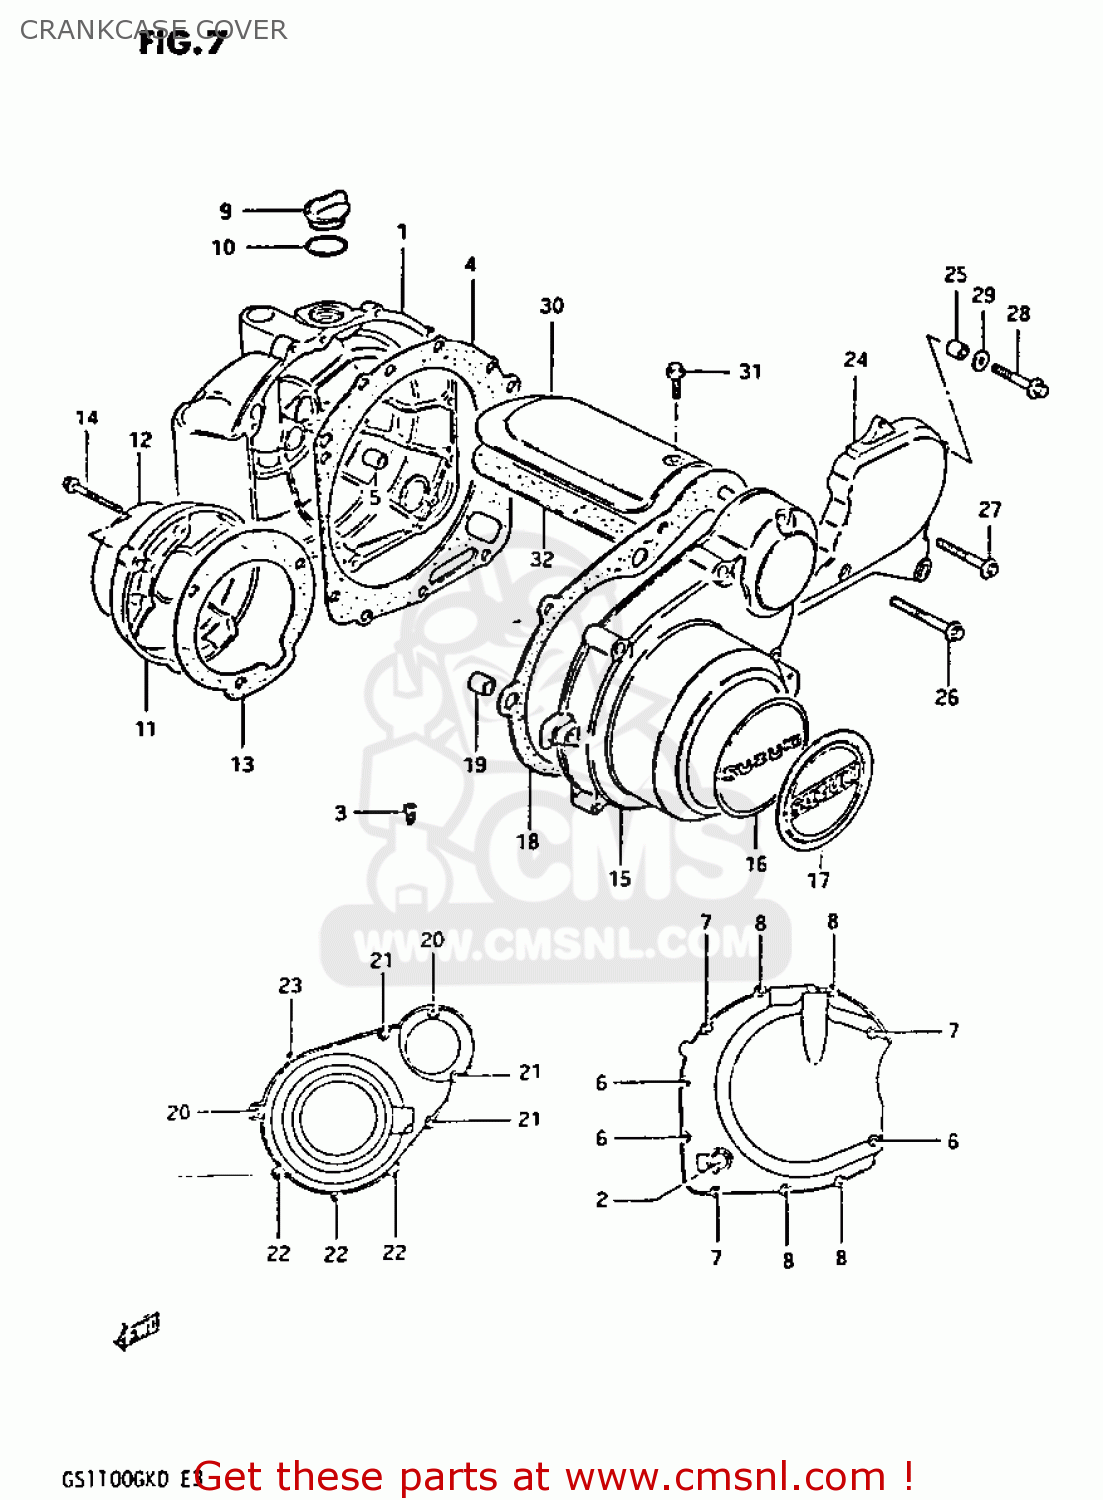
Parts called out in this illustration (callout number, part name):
1	COVER,CLUTCH
2	LENS,OIL LEVEL CHECK
3	JET
4	GASKET,MAGNETO COVER (NAS)
5	PIN
6	BOLT
7	BOLT
8	BOLT
9	PLUG SET
10	O RING(D:2.2,ID:32)
11	COVER,CONTACT BREAKER
12	EMBLEM,CONTACT BREAKER COVER
13	GASKET,CONTACT BREAKER COVER (NAS)
14	BOLT
15	COVER,MAGNETO
16	EMBLEM,MAGNETO COVER
17	EMBLEM,MAGNETO COVER
18	GASKET,MAGNETO COVER (NAS)
19	PIN
20	BOLT
21	BOLT
22	BOLT
23	BOLT
24	COVER,SECONDARY DRIVE
25	PIN
26	BOLT
27	BOLT
28	BOLT
29	WASHER
30	COVER,STARTER MOTOR
31	BOLT
32	GASKET,STARTING MOTOR COVER (NAS)
